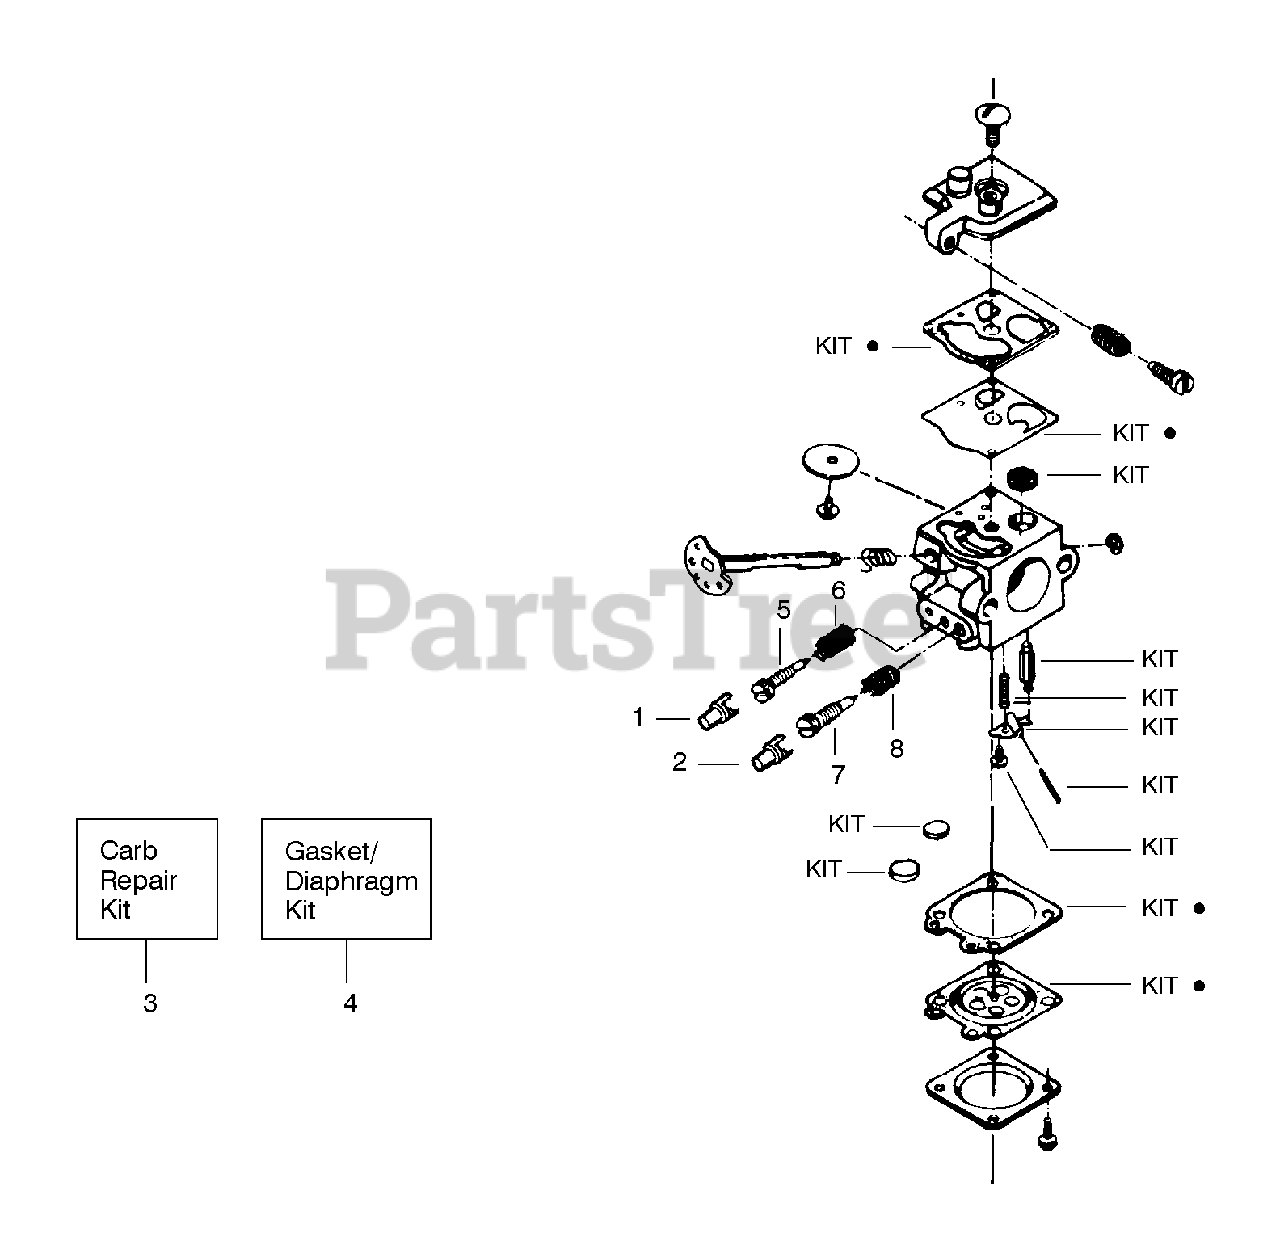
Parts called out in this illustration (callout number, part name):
1	Limiter Cap - High
2	Limiter Cap - Low
3	Carburetor Repair Kit
4	Gasket/Diaphragm Kit
5	Needle - Low Speed
6	Spring Needle - Low Speed
7	Needle - High Speed
8	Spring Needle - High Speed
